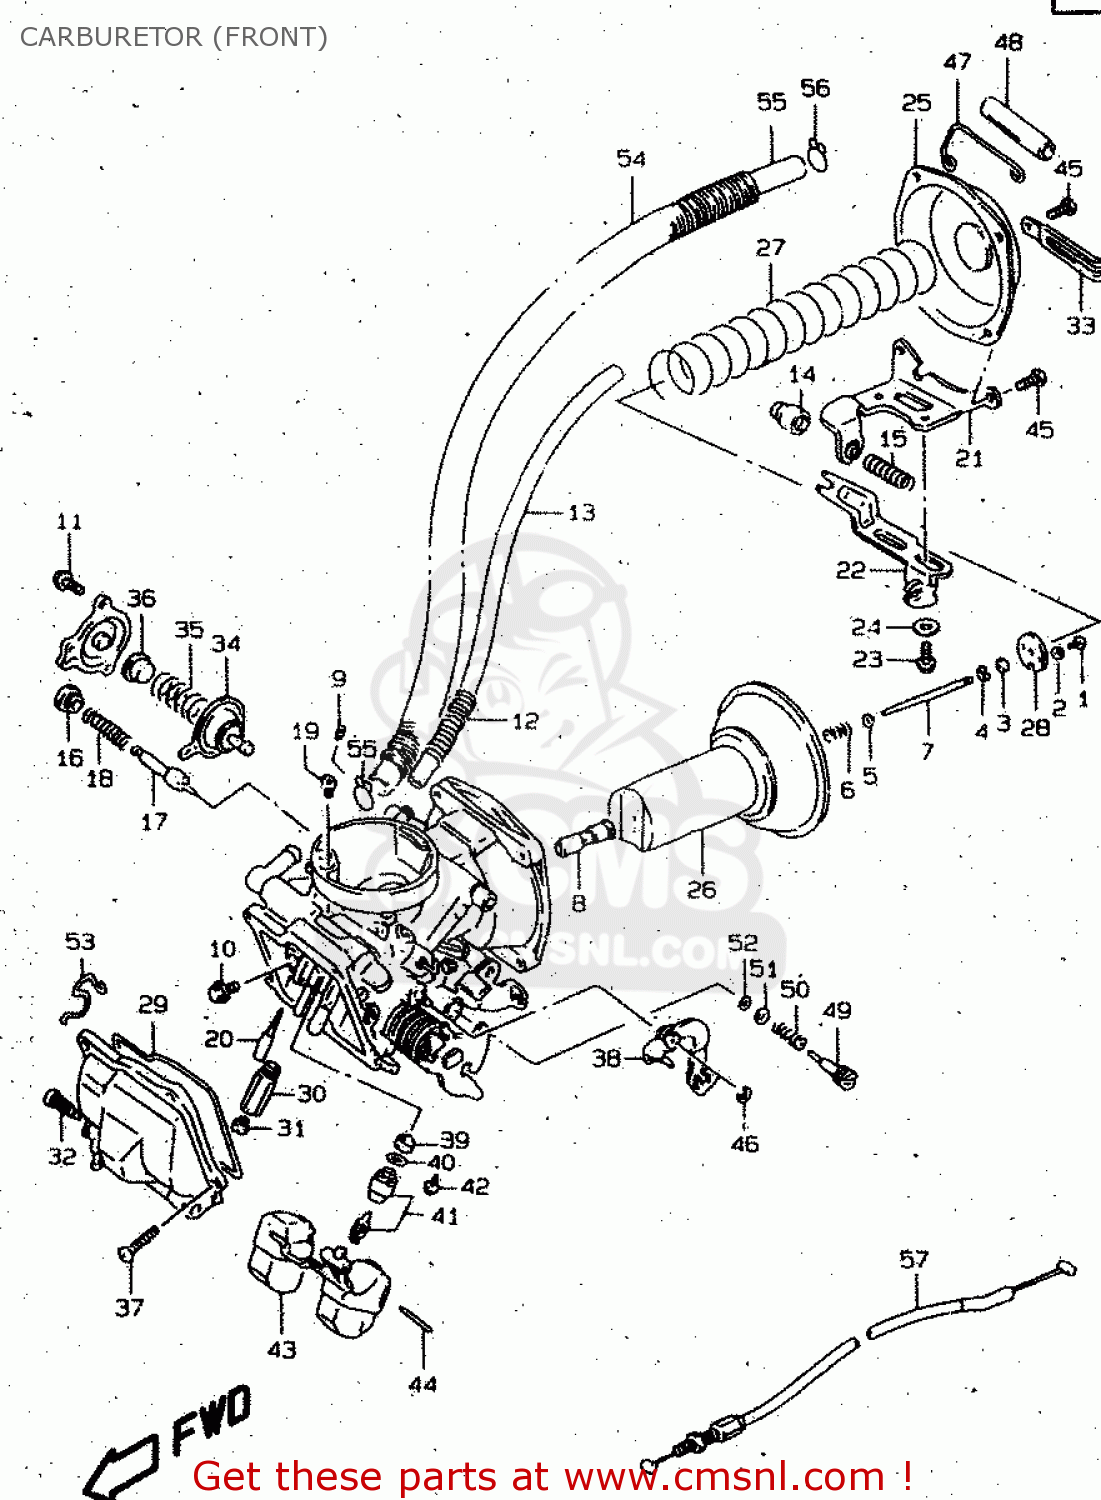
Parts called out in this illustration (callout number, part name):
1	SCREW
2	WASHER,LOCK
3	RING
4	CLIP
5	WASHER
6	SPRING
7	NEEDLE,JET
8	JET,NEEDLE
9	JET,PILOT AIR,1.4
10	SCREW
11	SCREW
12	SPRING
13	HOSE(5X8.2X600)
14	CAP
15	SPRING
16	HOLDER,GUIDE
17	PLUNGER
18	SPRING
19	JET,PILOT
20	JET,PILOT(50)
21	BRACKET
22	PLATE
23	SCREW
24	WASHER
25	COVER,DIAPHRAGM
26	DIAPHRAGM ASSY
27	SPRING,DIAPHRAGM
28	PLATE
29	O RING,FLOAT CHAMBER
30	HOLDER,MAIN JET
31	JET,MAIN(125)
32	SCREW,DRAIN
33	CLAMP
34	DIAPHRAGM ASSY
35	SPRING
36	PLATE
37	SCREW
38	LEVER ASSY
39	FILTER
40	O-RING,NEEDLE VALVE
41	VALVE ASSY,NEEDLE
42	SCREW
43	FLOAT
44	PIN,FLOAT
45	SCREW
46	E RING
47	CLIP
48	HOSE(6X10X600)
49	SCREW,PILOT
50	SPRING
51	WASHER
52	O RING,PILOT AIR SCREW
53	CLAMP
54	HOSE
55	HOSE(6.5X11.5X600)
56	CLIP
57	CABLE,IDLE SYNCRO
